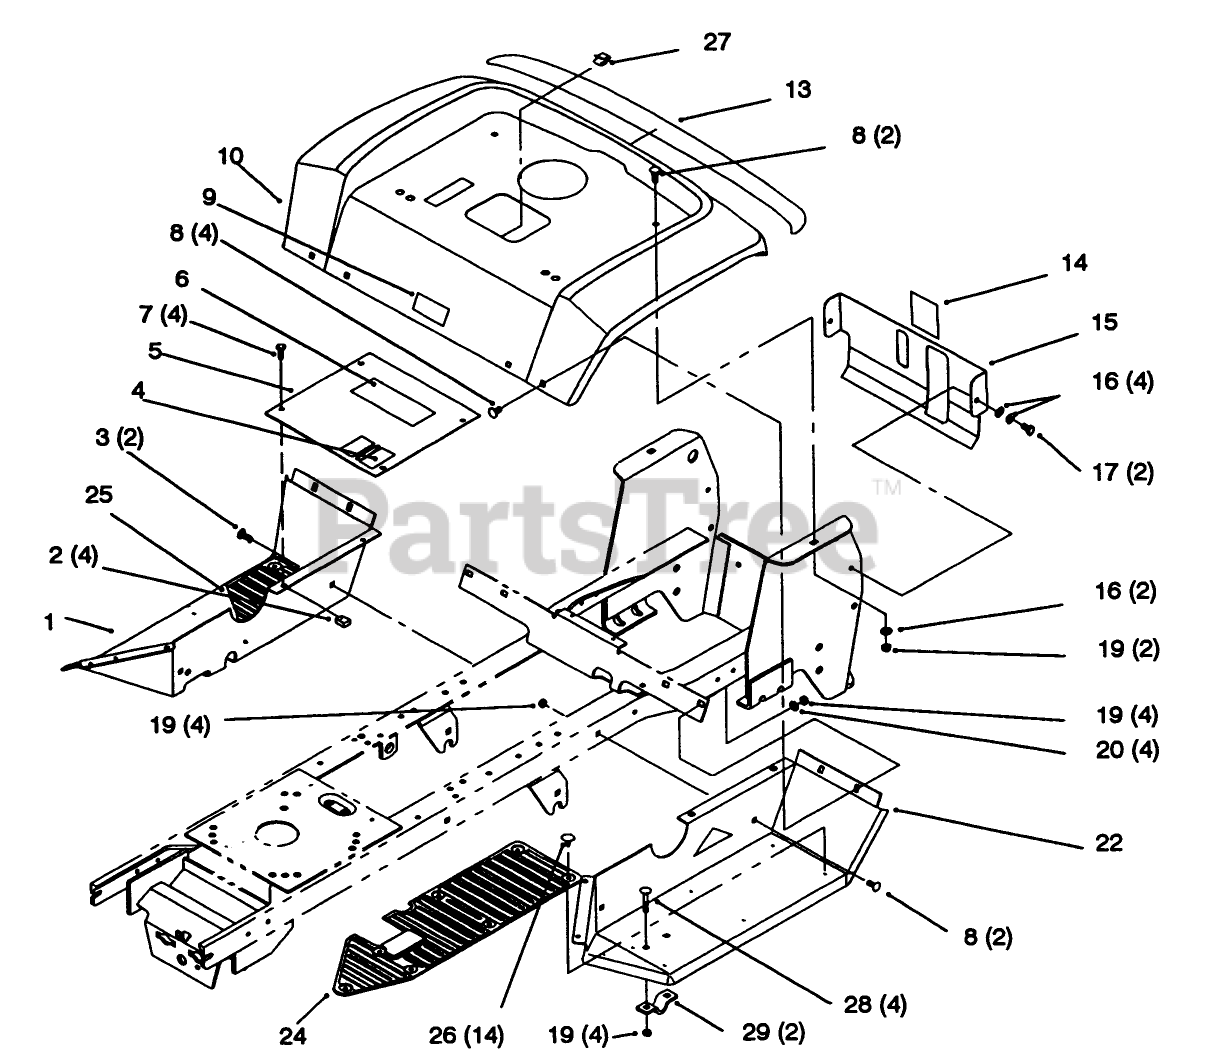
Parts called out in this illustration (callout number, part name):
1	FOOTREST-RH
3	SCREW-CARR
4	DECAL - HOC
5	PLATE/DECAL ASM-FOOTREST
6	DECAL-DANGER
7	SCREW-HH
8	BOLT-CARR
9	DECAL - USA
13	DECAL - REAR FENDER
14	DECAL-LEVEL, FUEL
15	COVER-REAR
16	WASHER-PLAIN
17	SCREW
19	NUT-LOCK, NI
20	WASHER-FLAT
22	LH FOOTREST
22	FOOTREST-LH
24	FOOTPAD-RH
24	FOOT MAT-RH
25	FOOTPAD-LH
25	FOOT MAT-LH
26	FASTENER-PANEL
27	CLIP-RETAINER, WIRE
29	CLAMP
